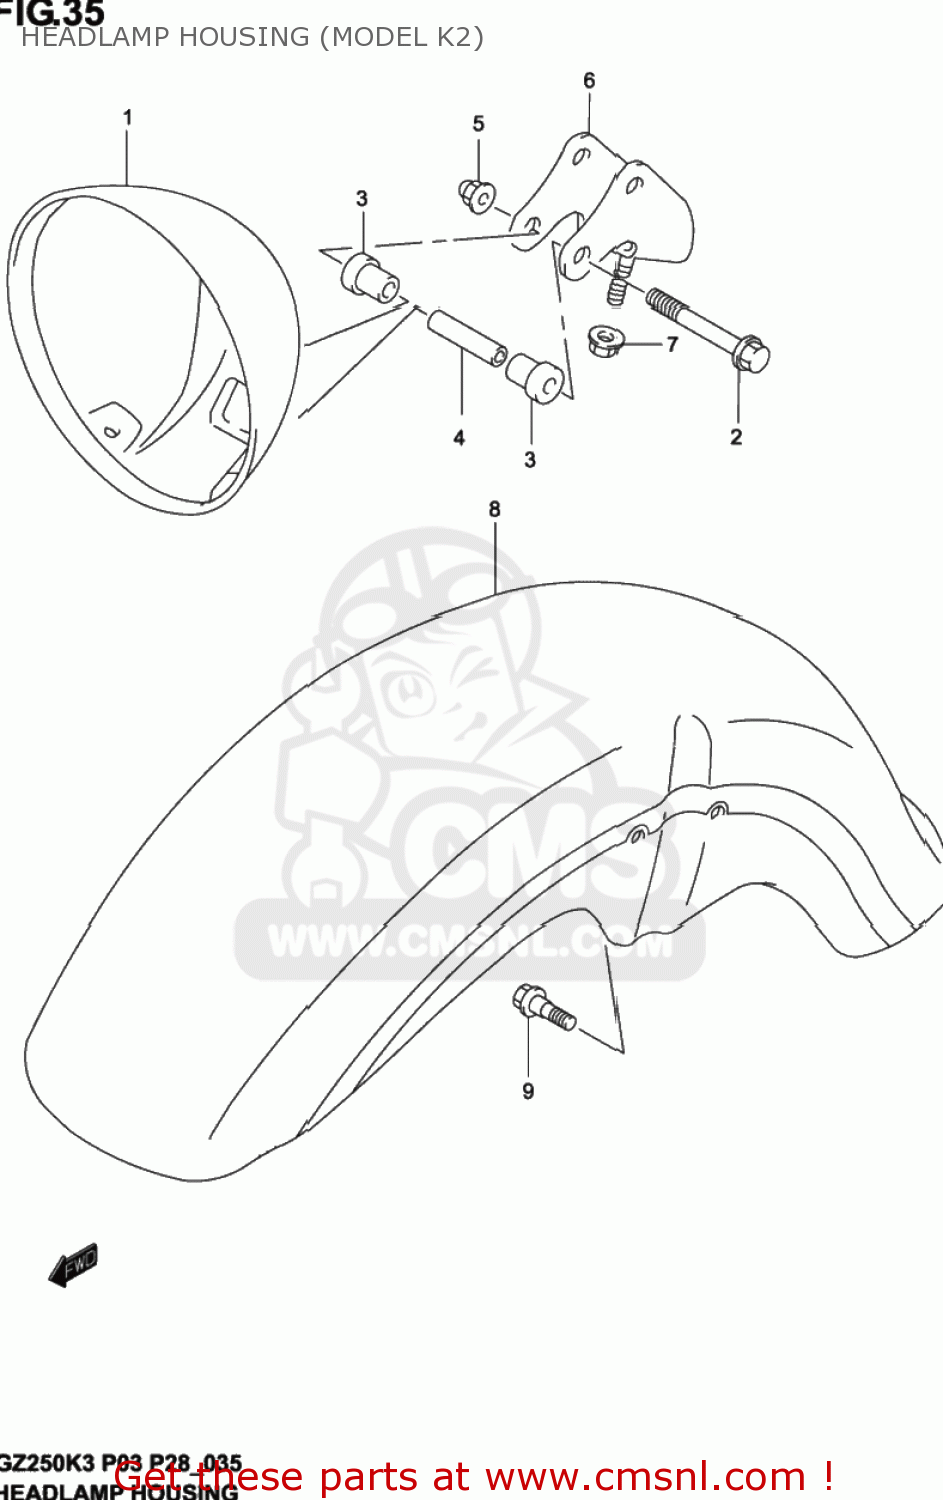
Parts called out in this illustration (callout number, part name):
1	HEADLAMPHOUSIN
2	BOLT
3	CUSHION,HEADLAMP HOUSING
4	SPACER(6.5X9X38.3)
5	NUT
6	BRACKET,HEADLAMP HOUSING
7	NUT
8	FENDER,FR
9	BOLT(6X16)
